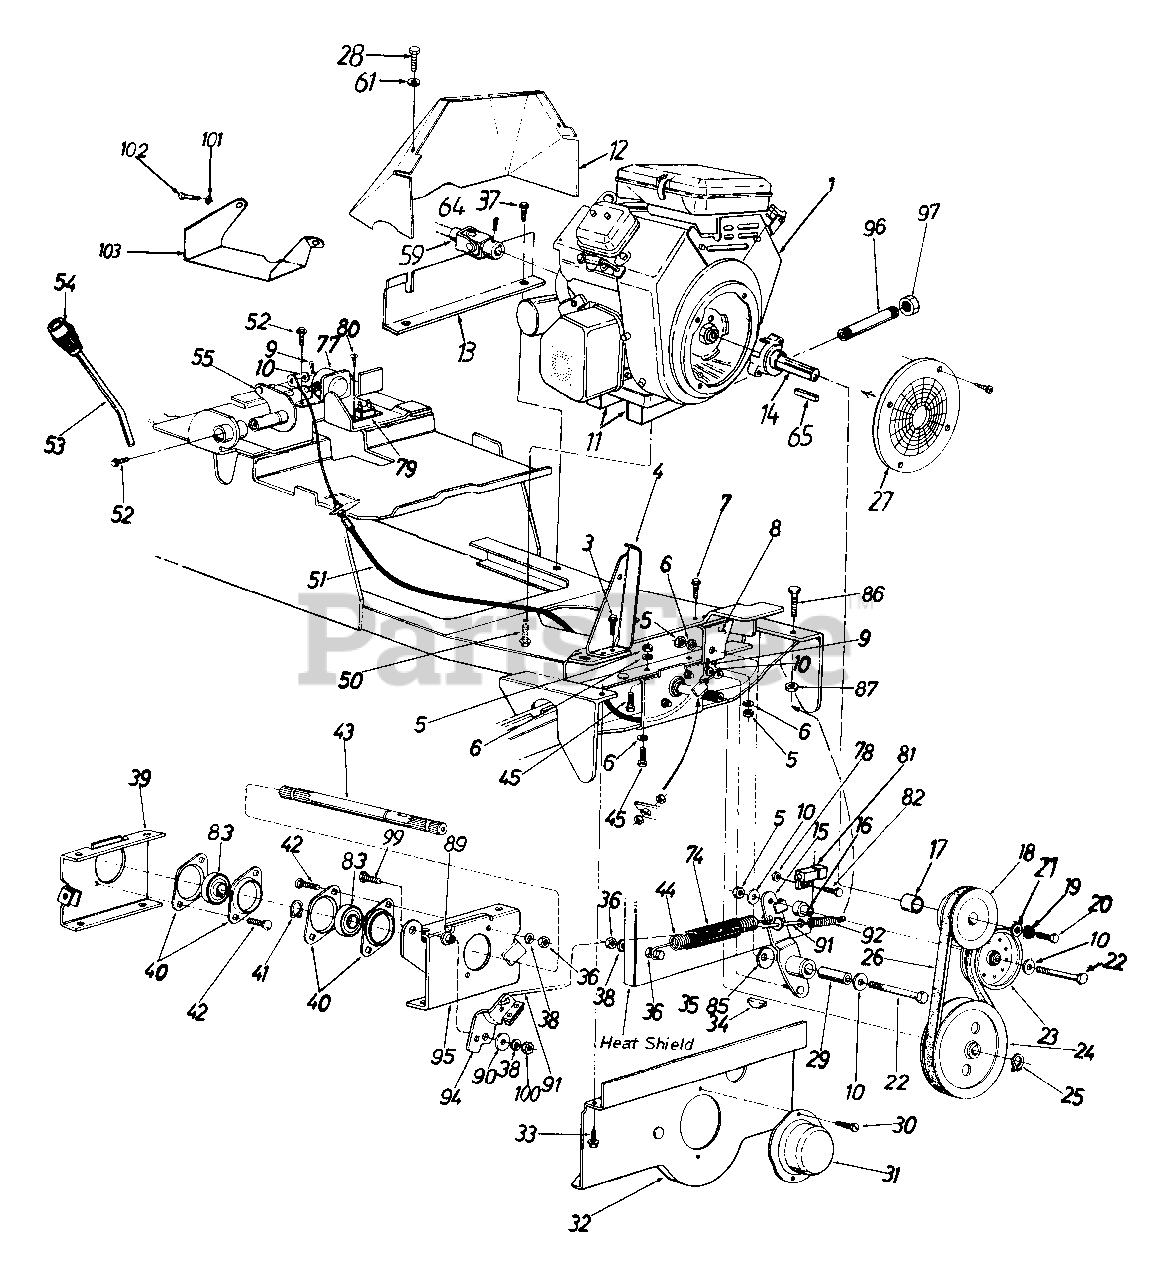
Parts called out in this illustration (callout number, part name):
1	Engine
3	Hex Wash. Hd. Self-Tap Scr. 1/4-20 x .75" Lg.
6	L-Wash. 3/8" I.D.
7	Hex Wash. Hd. Self-Tap Scr. 5/16-18 x .75" Lg.
10	Fl-Wash. .38" I.D. x 1.25" O.D. x .100" Thk.
11	Engine Spacer Bar
14	Crankshaft Ext.
15	PTO Idler Ass'y.
16	Idler Adapter
17	Pulley Spacer
18	Engine PTO - Pulley
19	L-Wash. 3/8" I.D.
20	Hex Bolt 3/8-24 x .88" Lg.
21	Fl-Wash. 3/8" I.D. x 1.37" O.D.
22	Hex Bolt 3/8-16 x 2.50" Lg.
23	Flat Idler Pulley
24	1/2" V-Pulley 7.00" O.D. (PTO)
25	Snap Ring
26	V-Belt (PTO)
27	Engine Screen
28	Hex Bolt M6-1.0 x 10 MM Lg.
29	Spacer .375" I.D. x .62" O.D. x 1.830" Lg.
30	Hex "B" Tap Scr. #10 x .50" Lg.
31	PTO Cup
34	#91 Hi-Pro Key
35	Hex Bolt 5/16-18 x 1.25" Lg.
36	Hex Nut 5/16-18 Thd.
37	Hex Wash. Hd. Tap Scr. 5/16-18 x .5" Lg.
38	L-Wash. 5/16" I.D.
40	1.00" Dia. Brg. w/Flangette
41	Snap Ring
42	Carr. Bolt 5/16-18 x .75" Lg.
43	Spline Shaft
44	Extension Spring (PTO Clutch)
45	Hex Scr. 3/8-16 x 1.00" Lg.
50	Hex L-Wash. TT-Tap Scr. 3/8-16 Thd.
51	PTO Control Cable
52	Hex Wash. Hd. TT-Tap Scr. 1/4-20 x .75" Lg.
53	PTO Handle
54	Shift Knob
55	PTO Actuator Lever Ass'y.
59	Universal Drive Shaft Comp.
61	Fl-Wash. .281" I.D. x .5" O.D.
64	Set Scr. 5/16-18 x .38" Lg.
65	Sq. Key 1/4" x 2.00" Lg.
74	Spring Cover Tubing (PTO Clutch)
77	Solenoid
78	Hex Bolt 1/4-20 x 1/2" Lg.
79	Circuit Breaker
80	Truss Mach. Scr. #10 x .50" Lg.
81	Safety Switch (PTO)
82	L-Wash. 1/4" I.D."
83	Ball Bearing
84	Muffler Ass'y. Comp. - L.H.
85	Bell-Wash, .39" I.D. x 1.13"
86	Hex Bolt 3/8-16 x 1.5" Lg.
87	Hex Cent. L-Nut 3/8-16 Thd.
89	Shoulder Spacer
90	Fl-Wash. .33" I.D. x 1.25" O.D.
91	PTO Brake Rod
92	Extension Spring 2.15" Lg.
93	PTO Idler Arm Ass'y.
94	Brake Ass'y.
95	PTO Brg. Retainer Brkt. Ass'y.
96	Pipe Nipple 3/8" x 5" Lg.
97	Oil Drain Cap
99	Hex Bolt 5/16-24 x .75" Lg.
100	Hex Nut 5/16-24 Thd.
101	L-Wash. 7/16" I.D.
102	Hex Bolt 7/16-14 x .75" lg.
103	Heat Shield
